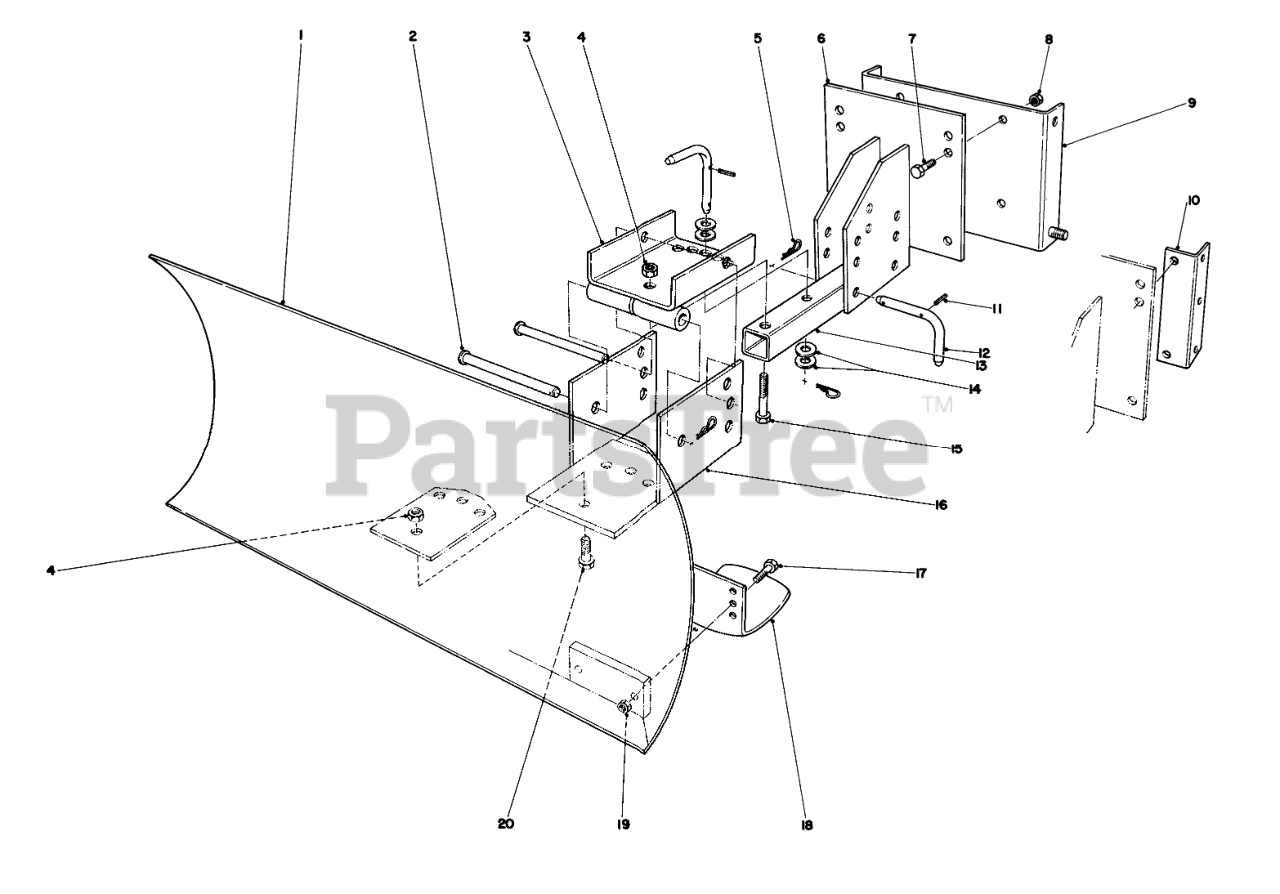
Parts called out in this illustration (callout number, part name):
1	Blade
2	PIN-CLEVIS
3	Swivel Bracket
4	1/2-13 CONELOCK NUT
5	PIN-HAIR
6	Mounting Plate
7	SCREW-HH
8	NUT-LOCK, CONE
9	Mounting Plate (Used with 826 & 1132 Units only)
10	Mounting Rail (used with 421 units only)
11	PIN-SPRING
12	Pivot Pin (Incl. Ref. #11)
13	Blade Tongue
14	WASHER-FLAT
15	SCREW-HH
16	Blade Adjustment
17	SCREW-HH
19	NUT-LOCK, CONE
20	SCREW-HH
